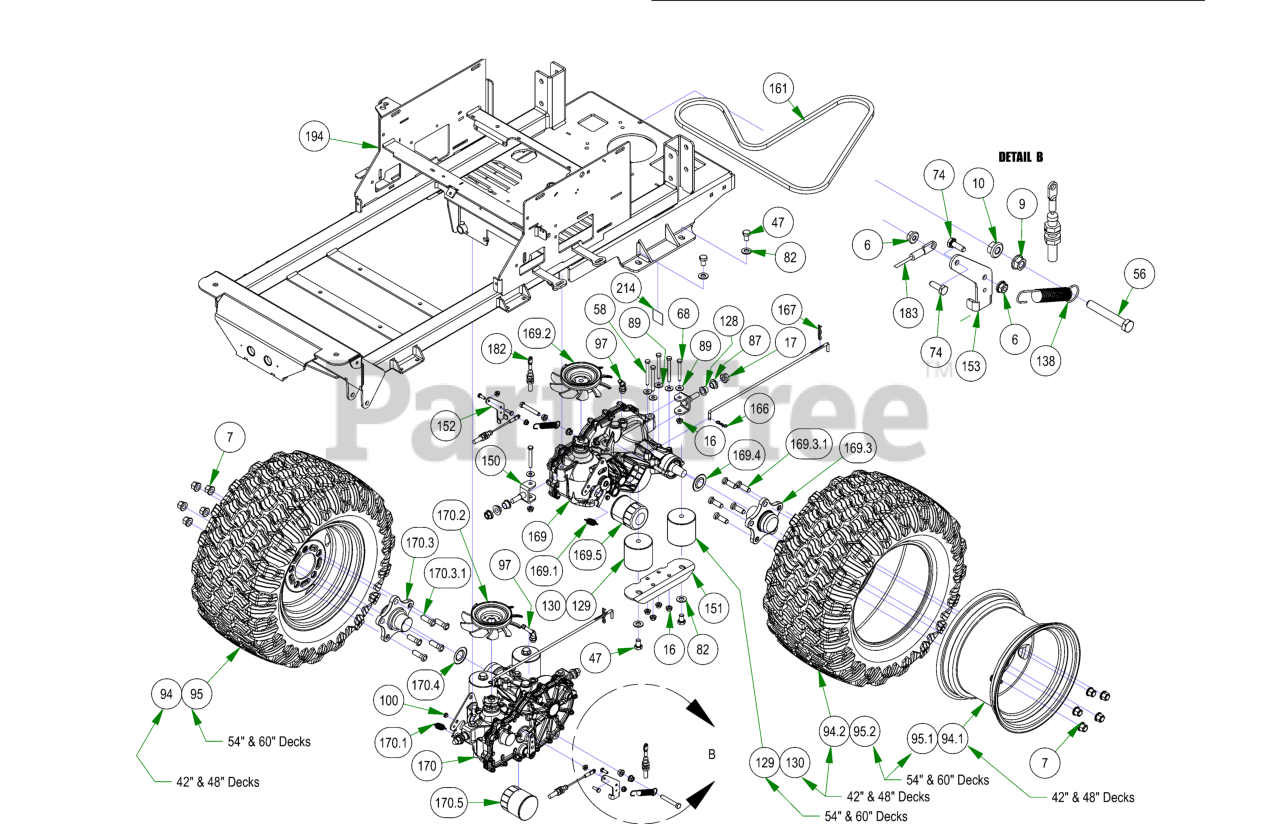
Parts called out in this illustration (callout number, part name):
6	1/4-20 NYL INSERT FLANGE LOCKNUT ZINC
7	Acorn Lug Nut
9	3/8-16 HEX SERRATED FLANGE NUT HARD/ZINC
10	3/8-16 NYLON INSERT FLANGE LOCKNUT (GR.F) ZINC
16	5/16-18 NYLON INSERT FLANGE LOCKNUT ZINC
17	1/2-13 NYLON INSERT FLANGE LOCKNUT ZINC
47	1/2-13 X 3/4 HEX CAP SCREW (GR.5) ZINC
56	3/8-16 X 2-1/2 HEX TAP BOLT (GR.5) ZINC Fully Threaded
58	5/16-18 X 3 HEX CAP SCREW (GR.5) ZINC
63	3/8-16 X 1 CARRIAGE BOLT (GR.5) ZINC
68	5/16-18 X 2-1/2 HEX CAP SCREW (GR.5) ZINC
74	1/4-20 X 3/4 HEX CAP SCREW (GR.5) ZINC
82	1/2 SAE FLAT WASHER (1-1/16" OD) GR.8 ZINC YELLOW
87	.525 ID SHOULDER WASHER NYLON
89	5/16 USS FLAT WASHER (7/8 OD) ZINC
94	23x9-12 Reaper Turf Tire & Wheel Assembly
94.1	12x7" Black Wheel
94.2	23x9-12 Reaper Turf Tire Only
95	23x11-12 Reaper Turf Assembly
95.1	12x8.5 Black Wheel
95.2	Tire, 23/11x12 Reaper Turf
97	ZT Fitting, 3/8 x 3/8 45 Degree, 4603-6-6
100	Drive Arm Transaxle Spacer
115	Neutral Rod
128	.627 ID X .753 OD X .500 LGTH X 1.000 FLG OD X .094 FLG THICK FLANGED BEARING OIL-IMPREG BRNZ
129	Vibration Mount-Green Dot
130	Vibration Mount- Red Dot
138	Brake Return Spring
150	Maverick Rear Transaxle Pivot Bracket
151	Rear Suspension Transaxle Mount
152	Brake Arm Ext (Left)
153	Brake Arm Ext (Right)
161	75.8" Pump Belt
167	Neutral Rod Clip
169	Compact Outlaw/Revolt Transaxle Left 3400
169.1	Gold Transaxle Spring
169.2	Fan/Pulley Kit for CZT Also for the 050-0075-01
169.3	5 Bolt Hub Kit
169.3.1	Transaxle Wheel Studs/ Drum Brake Studs
169.4	Seal Kit for 3400 Transaxle fits the 050-6000-01 / 050-6001-01
169.5	ZT Hydraulic Filter
170	Compact Outlaw/Revolt Transaxle Right 3400
170.1	Gold Transaxle Spring
170.2	Fan/Pulley Kit for CZT Also for the 050-0075-01
170.3	5 Bolt Hub Kit
170.3.1	Transaxle Wheel Studs/ Drum Brake Studs
170.4	Seal Kit for 3400 Transaxle fits the 050-6000-01 / 050-6001-01
170.5	ZT Hydraulic Filter
182	2021 Load Balanced Brake Cable 1
183	2021 Load Balanced Brake Cable 2
194	2023 Maverick Frame - Painted
214	Patent Decal
